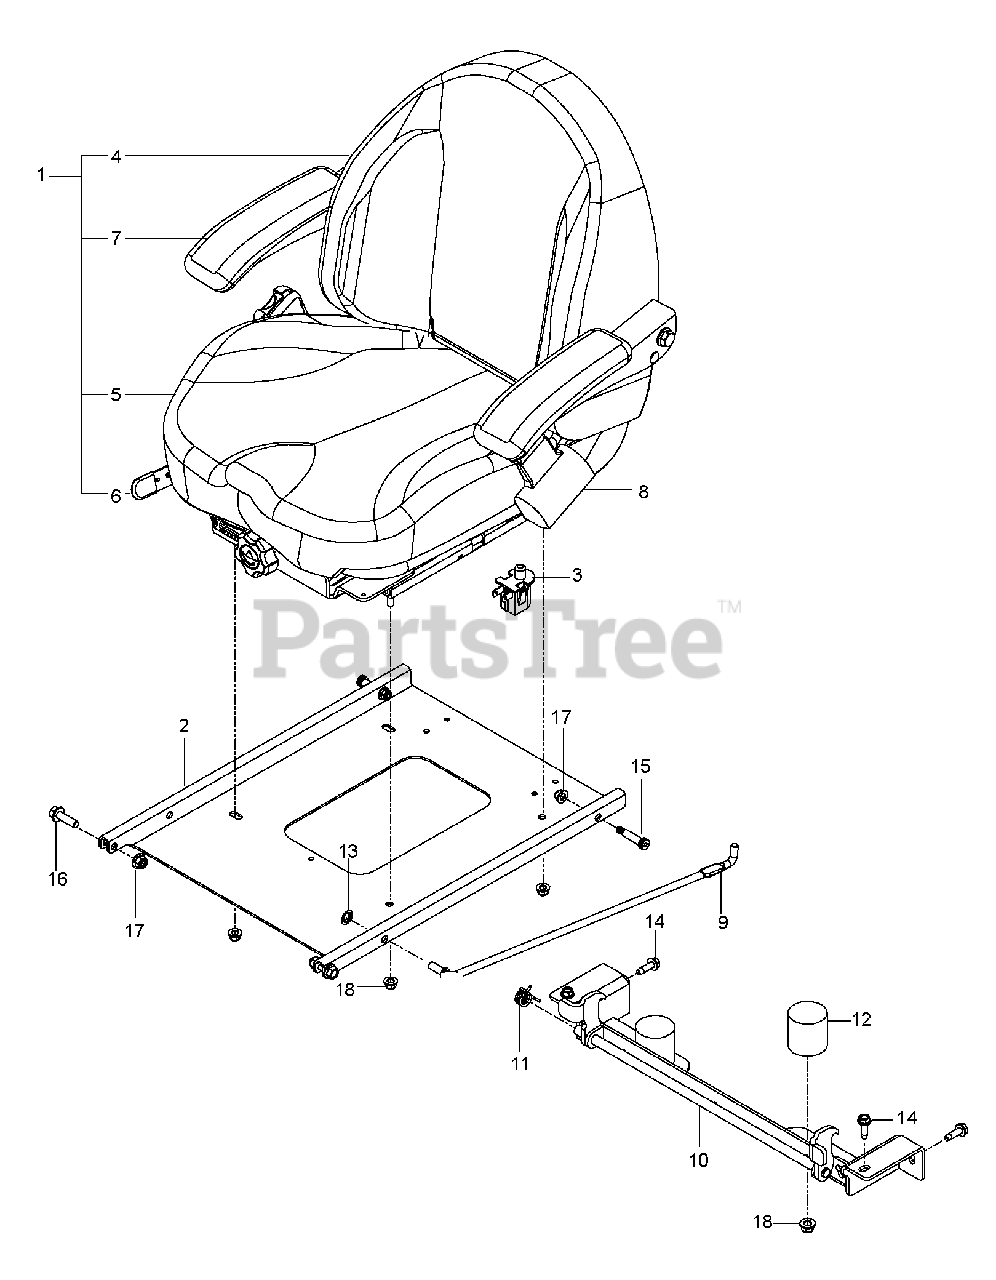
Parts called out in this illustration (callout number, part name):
1	SEAT, 1110 SUSPENSION
2	PAN, SEAT, BLACK
3	SEAT SWITCH
4	COVER, BACK
5	COVER KIT, CUSHION
6	TRACK KIT
7	ARMREST, LT
8	Seat Belt, Retractable
10	BRACKET.PNT.LATCH.SEAT.BUMPER
11	SPRING, TORSION
12	BUMPER, RUBBER
13	NUT 3/8 PALNUT RTNG BLK PHOS
14	RP BLT 5/16-18 X 1 THRD FORM D
15	BOLT, SHOULDER 3/8 X 1.25
16	HHFS 3/8-16 X 1.25 GD 5
17	NUT 3/8-16 HEX FLG NYLOC ZD
18	5/16-18 NYLOC FLANGE NUT
